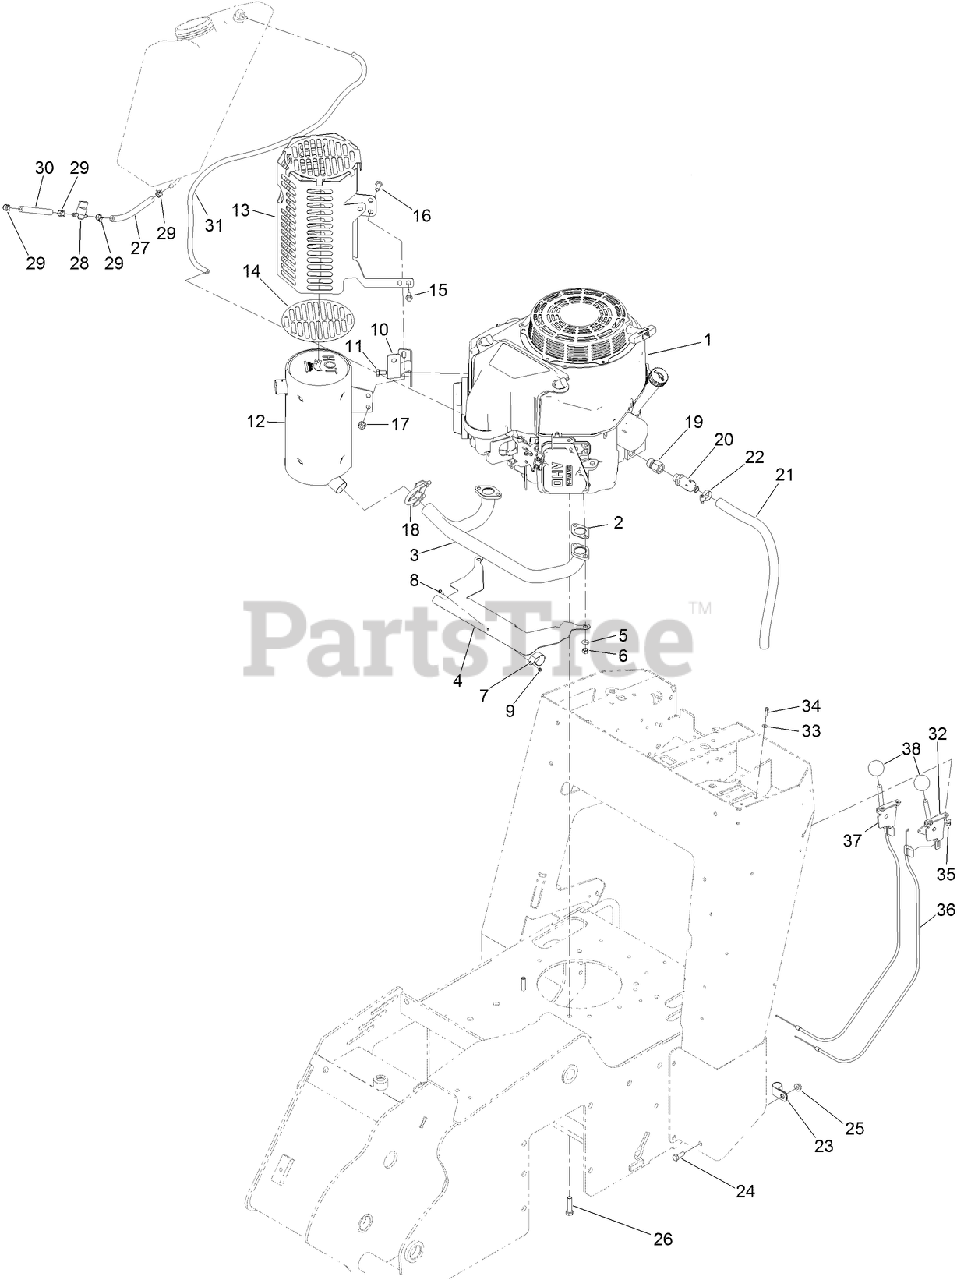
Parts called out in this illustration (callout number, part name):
1	ENGINE-KAWASAKI, FS481V
2	GASKET-EXHAUST
3	MANIFOLD-MUFFLER
4	PLATE-SHIELD, HEAT
5	WASHER-SPRING
6	NUT-HEX
8	SCREW-PAN
9	NUT-HEX
10	BRACKET-GUARD, MUFFLER
11	SCREW-HH
12	MUFFLER
13	GUARD-MUFFLER
14	FOIL-GUARD
15	SCREW-HHF
16	SCREW-HH
17	NUT-HF
18	CLAMP-MUFFLER
19	ADAPTER
20	VALVE-DRAIN, OIL
21	HOSE-VENT
22	CLAMP-HOSE
23	CLAMP-R
24	SCREW-HH
25	NUT-HF
26	SCREW-HH
27	HOSE-FUEL
28	VALVE-FUEL
29	CLAMP-HOSE
30	HOSE-FUEL
31	HOSE-VENT, TANK
32	LEVER-CONTROL
33	WASHER-FLAT
35	NUT-LOCK, NI
36	CABLE-CONTROL
37	LEVER-CONTROL
